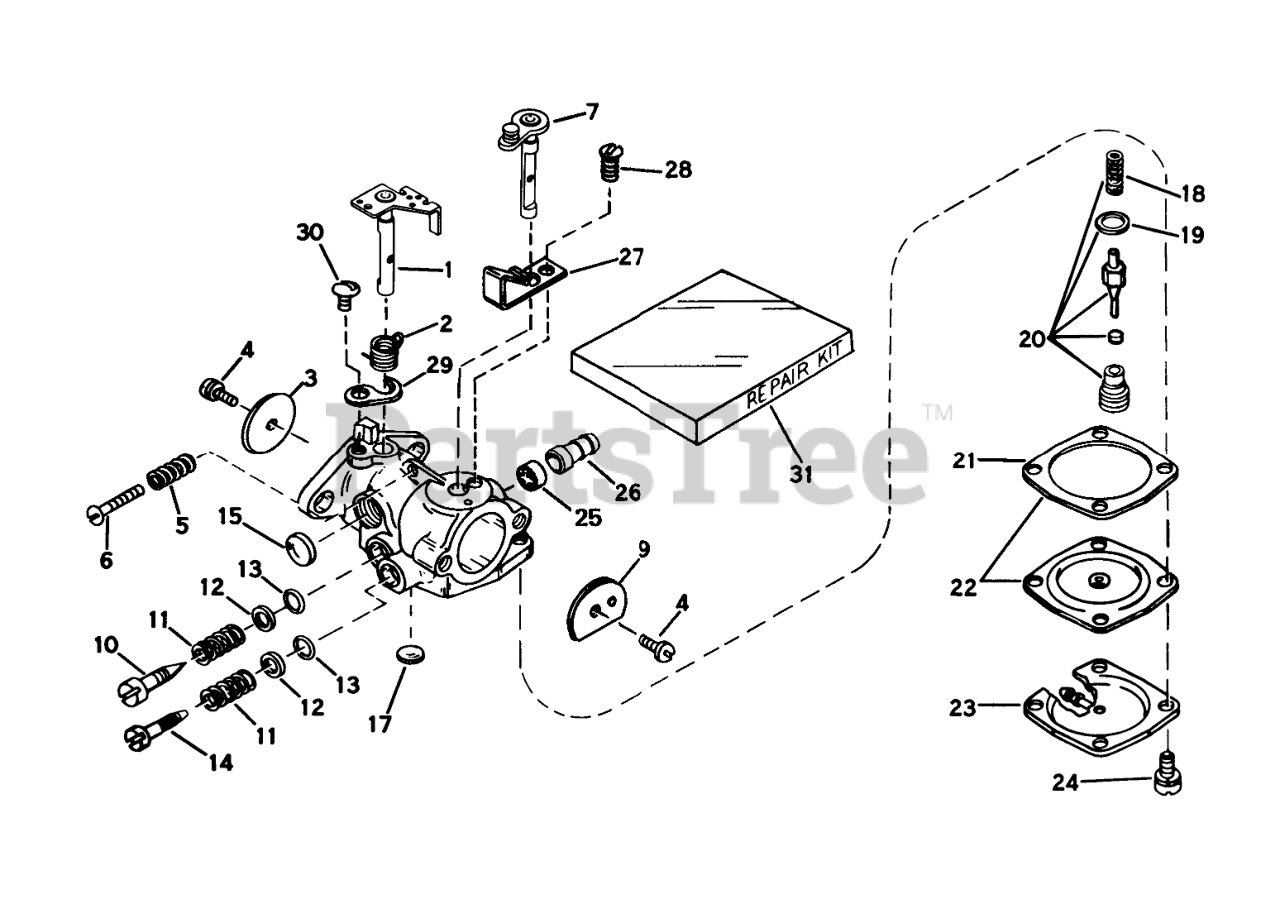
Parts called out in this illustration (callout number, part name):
1	Shaft & Lever Assy., Throttle
2	Spring Return
3	Shutter, Throttle
4	Screw-Shutter
5	Spring-Tension
6	Screw-Throttle Crack Screw / Idle Speed
7	Shaft & Lever Assy., Choke
9	Shutter-Choke
10	Screw-Idle Adjustment
13	"O"Ring
14	Screw Main Adjustment
15	Plug-Welch, Idle Mixture Well
17	Plug Welch
18	Spring-Valve
19	Gasket-Valve Seat
20	Inlet Needle, Seat, Spring & Gasket Assy. (Incl. Nos. 18 & 19)
21	Gasket-Diaphragm
22	Diaphragm Assy. (Incl. No. 21)
23	Cover, Diaphragm
24	Screw, Diaphragm Cover
25	Valve Check
26	Fitting, Fuel inlet
27	Spring, Detent
28	Screw Detent spring
29	Retainer, Throttle Shaft
30	Screw Detent spring
31	Repair Kit
